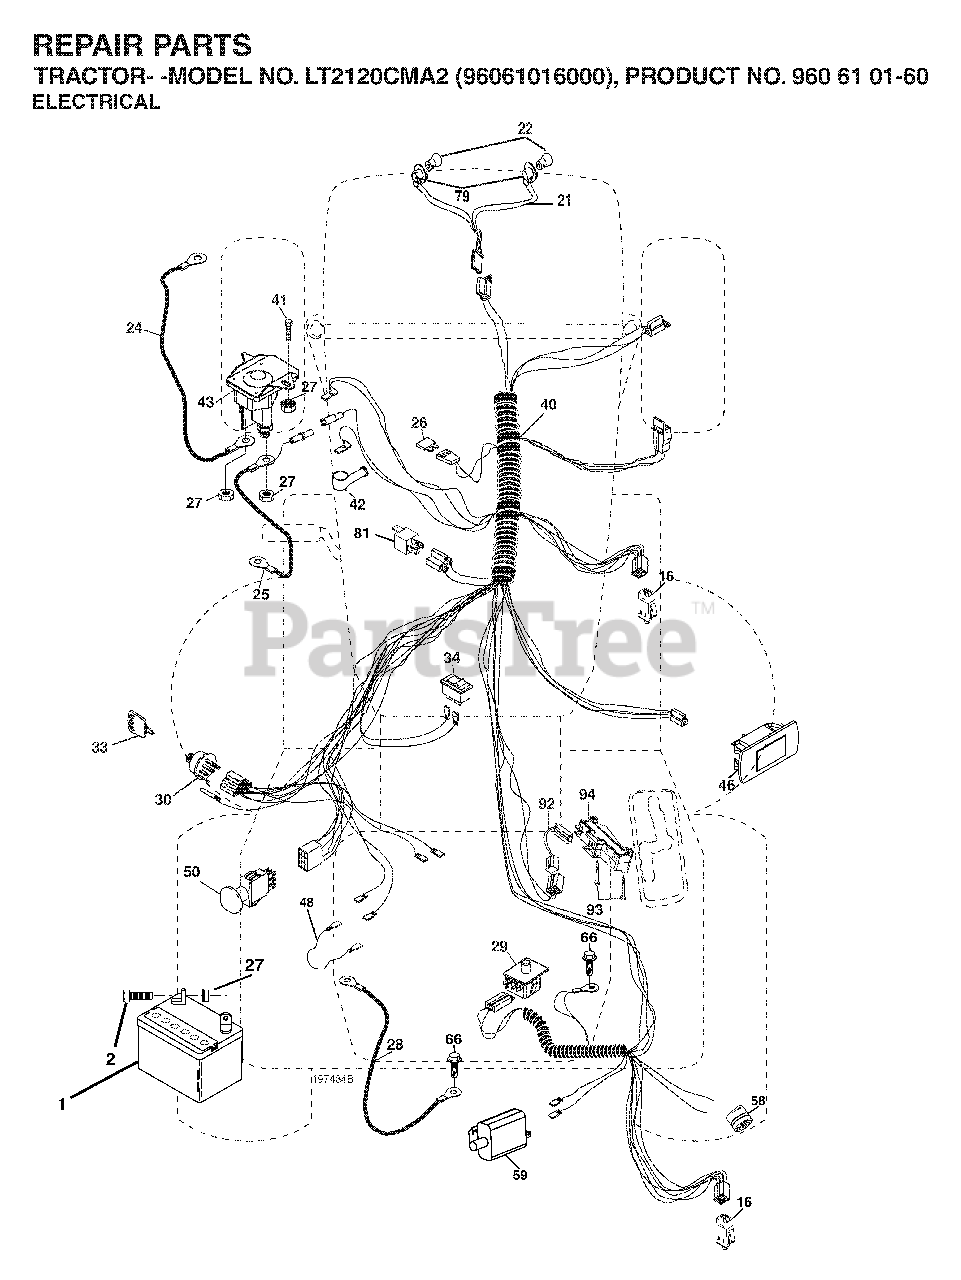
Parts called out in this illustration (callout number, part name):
1	BATTERY 12V .35 AMP
16	SWITCH INTERLOOK PUSH-IN
21	HARNESS.W/LIGHT SOCKET
22	LIGHTBULB
24	BATTERY CABLE GT
25	CABLE BATTERY
26	FUSE 20AMP
27	NUT
28	CABLE GROUND
29	SWITCH.SEAT.DP W/RAMPS
30	SWITCH.IGN.DELTA.W.LGH.ROS
33	KEY MLD GEN DELTA
34	SWITCH LT
42	TERMINAL COVER
43	SOLENOID.W/BRASS.PLUNG
46	GAUGE.SERVICEMINDER.HR
48	GUAGE.SRVCMNDR.HRMTR.
50	PTO SWITCH
58	BUZZER
79	BULB HOLDER ASM.
81	RELAY.ASSY.T
92	HARNESS.PIGTAIL.CONSLE
93	SCREW.PLASTITE
94	MODULE.REVERSE.ROS
